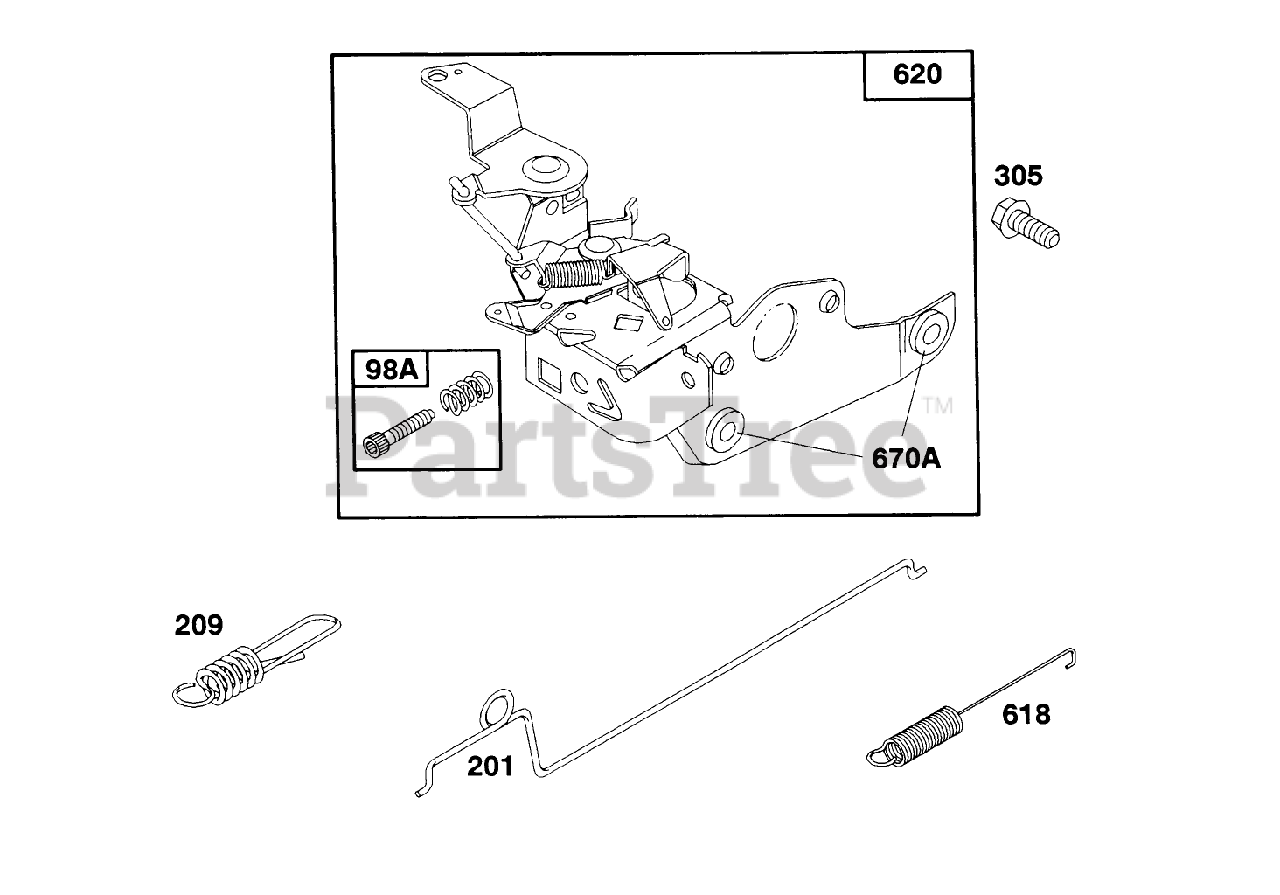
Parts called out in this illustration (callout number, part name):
98A	Screw Assy.
201	Link-Govemor
209	Spring-Govemor
305	Screw-Sem
618	Spring-Choke
620	Bracket Assembly
670A	Spacer
